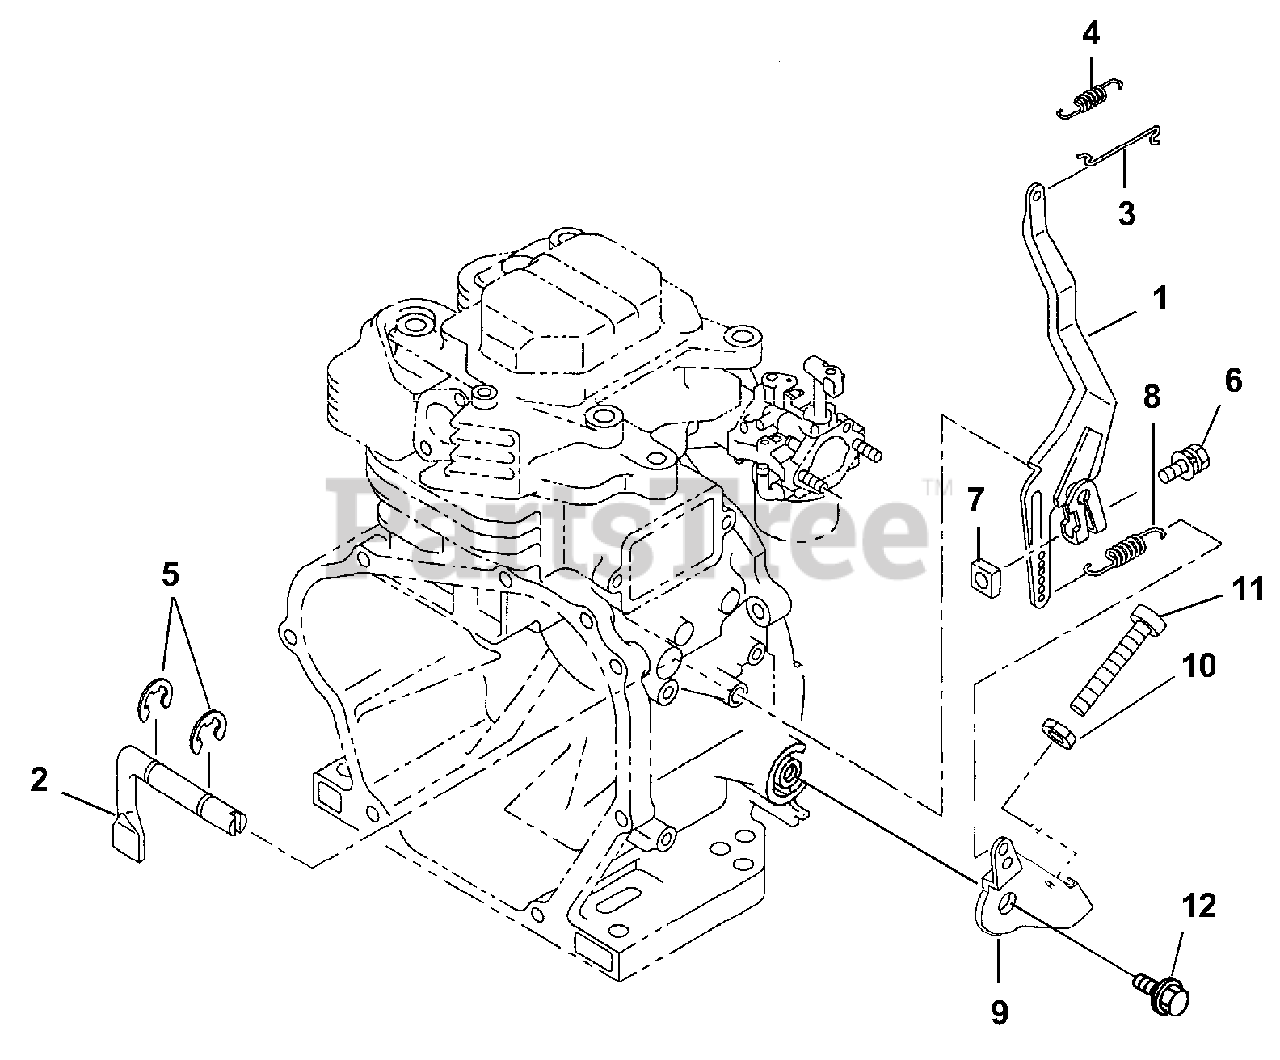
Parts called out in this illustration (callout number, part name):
1	Governor lever
2	Governor shaft
3	Governor rod
4	Rod spring
5	Clip
6	Bolt and Washer AY
7	Nut
8	Governor spring
9	Speed control lever
10	Nut
11	Screw, panhead
12	Bolt & Washer
